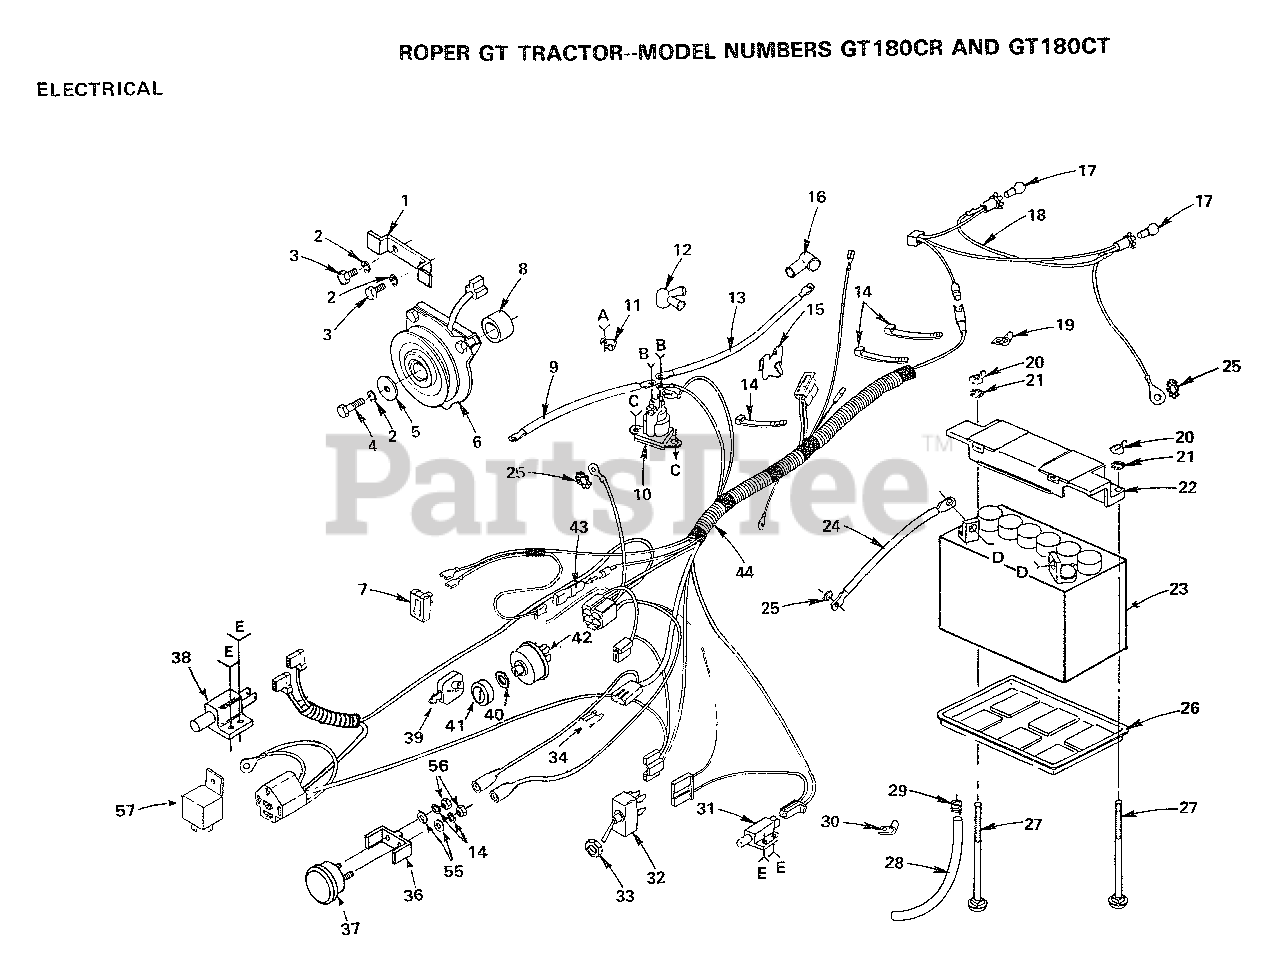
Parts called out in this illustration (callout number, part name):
1	STOP CLUTCH T
2	LOCKWASHER
3	BOLT
4	BOLT
5	WASHER GT
6	CLUTCH.ELECTRIC.T
8	SPACER-CLUTCH GT
9	CABLE-BATTERY T
12	TERM COVER DUAL
15	CLIP-HARNESS
18	HARNESS T
19	CLIP GT
21	LOCKWASHER GT
24	CABLE T
25	LOCKWASHER
26	"TRAY T, BATTERY"
27	BOLT
29	HOSE CLAMP T
30	CLIP GTV
31	SWITCH-INTER. GT
32	SWITCH.PTO.T
33	HEX NUT T
34	FUSE-30 AMP
37	AMMETER T
38	SWITCH T
44	HARNESS-IGNITION
55	WASHER
57	RELAY ASSY T
